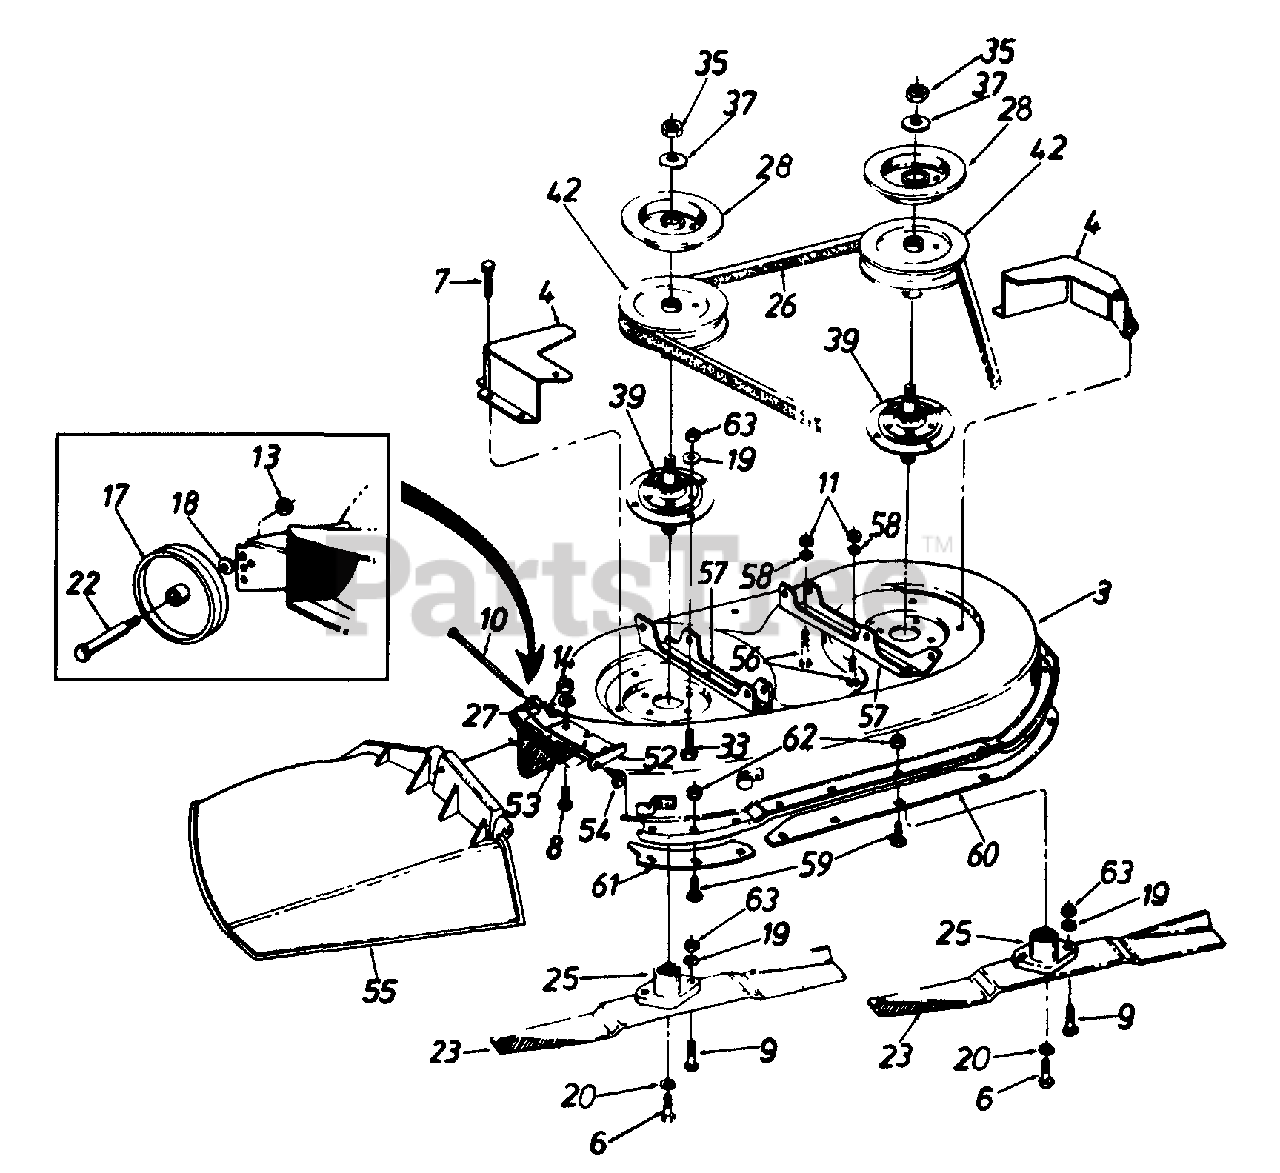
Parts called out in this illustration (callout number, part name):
6	Hex Bolt 3/8-24 x 1.0" Lg. (Gr. 5)
7	Hex Wash. Hd. TT-Tap Scr. 1/4-20 x .5" Lg.
8	Hex Bolt 1/4-20 x .62"
9	Hex Bolt Special 5/16-24 x 1.0"
10	Hinge Pin
11	Hex Nut 5/16-24 Thd.
13	Hex Top L-Nut 3/8-16 Thd.
14	Hex Nut 1/4-20 Thd.
17	Deck Wheel - 5"
18	Bell-Wash..40" I.D. x .88" O.D.
19	L-Wash. 5/16" I.D.
20	L-Wash. 3/8" I.D. - H.D.
22	Shld. Bolt .498" Dia. x 1.53"
23	High-Lift Blade
25	Blade Adapter
26	V-Belt
27	Bell-Wash. 1/4" I.D.
28	Brake Disc
33	Rib Neck Bolt 5/16-24 x 75" Lg.
35	Hex Jam Nut 5/8-18 Thd.
37	L-Wash. 5/8" I.D.
39	Blade Spindle Ass'y. Comp.
42	5.5" Dia. Pulley
52	Hinge Mtg Brkt.
53	Torsion Spring
54	Push Nut
55	Chute Ass'y. Comp.
56	Hex Bolt 5/16-24 x 75" Lg.
59	Carr. Bolt 1/4-20 x .5" Lg
62	Hex Sems Nut 1/4-20 Thd.
63	Hex Nut 5/16-24 Thd. (Gr. 5)
